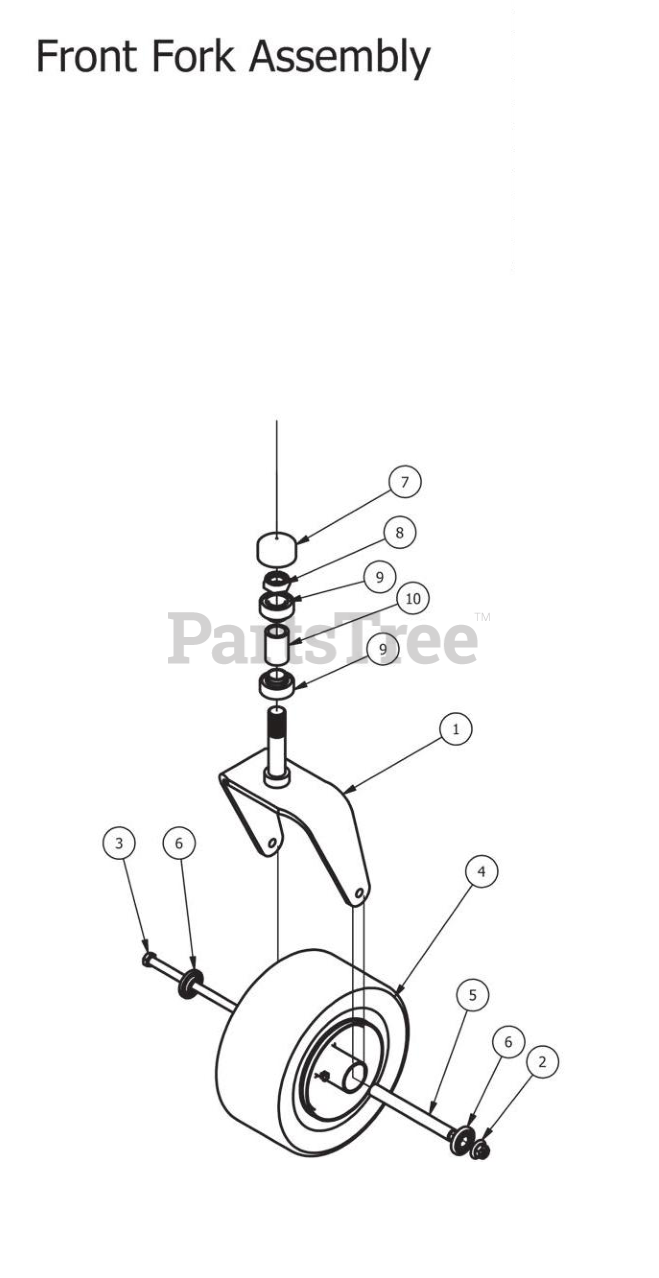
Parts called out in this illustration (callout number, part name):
1	Front Fork
2	1/2-13 Nylon Flange Nut-Orange
3	1/2" x 9" Bolt
4	Tire and wheel assembly
5	Front Wheel Spanner
6	Wheel Bearing
7	Rubber Bearing Cap
8	1" Fine Thread 1/2 Nut
9	Caster Bearing -MZ, 2009 & up
10	ZT/CZT Caster Bearing Spacer
